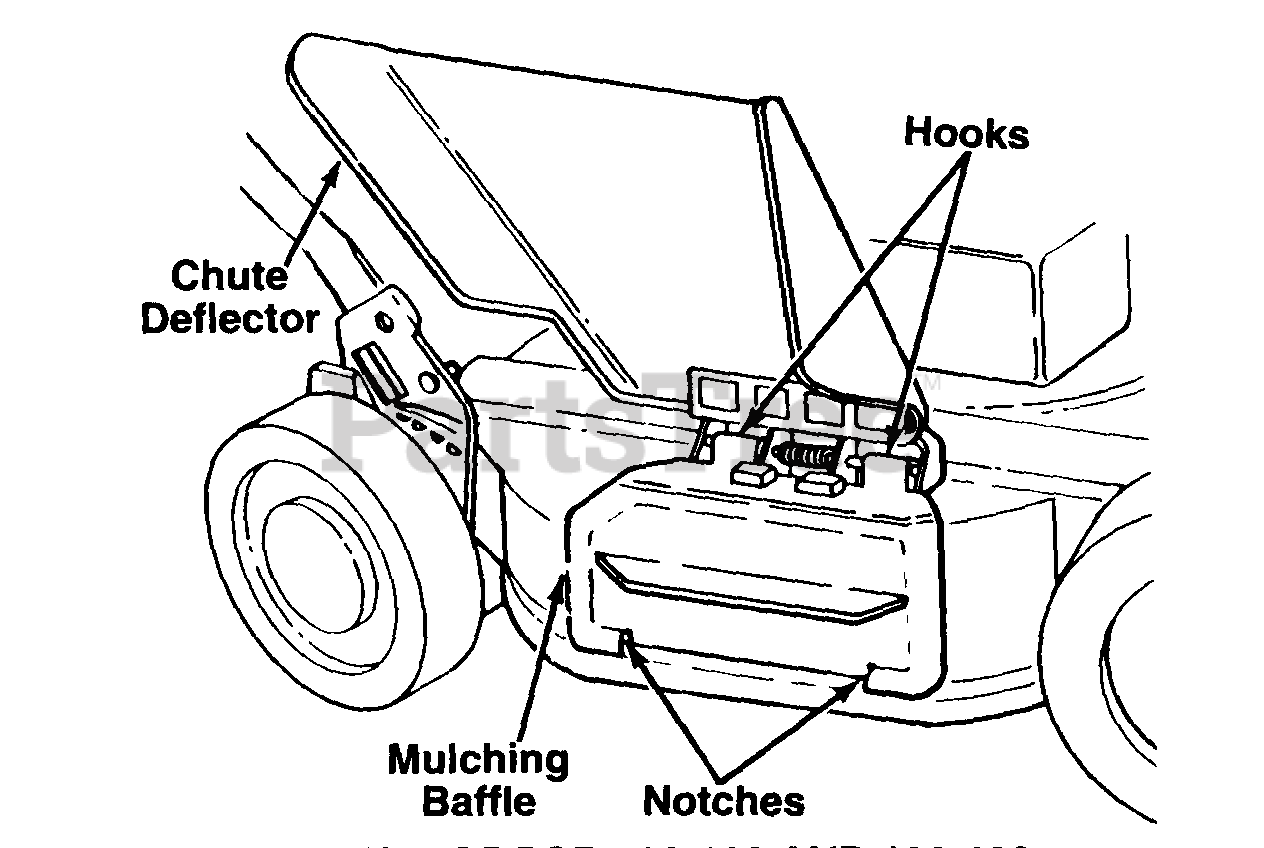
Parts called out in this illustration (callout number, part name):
1	20" Mulching Blade
2	22" Mulching Blade
3	Mulching Baffle
